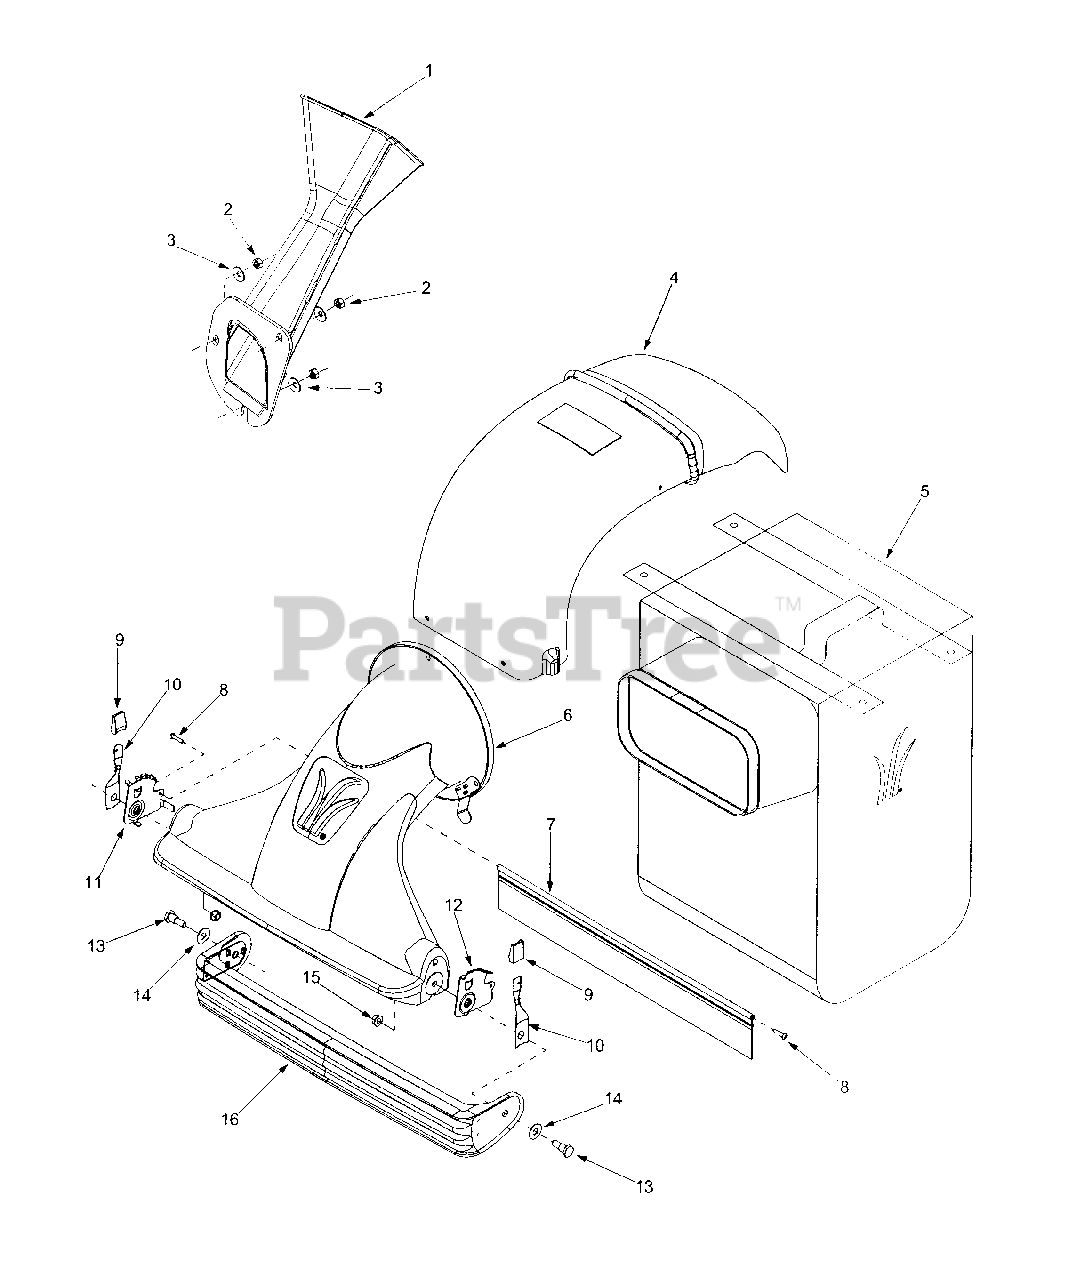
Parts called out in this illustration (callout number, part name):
2	Hex Nut 5/16-18
3	Bell Washer .340 ID x .872 OD
4	Discharge Chute
6	Nozzle Assembly
7	Nozzle Flap
8	Screw
9	Height Adjustment Knob
10	Spring Lever
11	Index Bracket RH
12	Index Bracket LH
13	Shoulder Screw
14	Flat Washer .510 x 1.12 x .060
15	Hex Flange Lock Nut 3/8-16
16	Door Assembly
